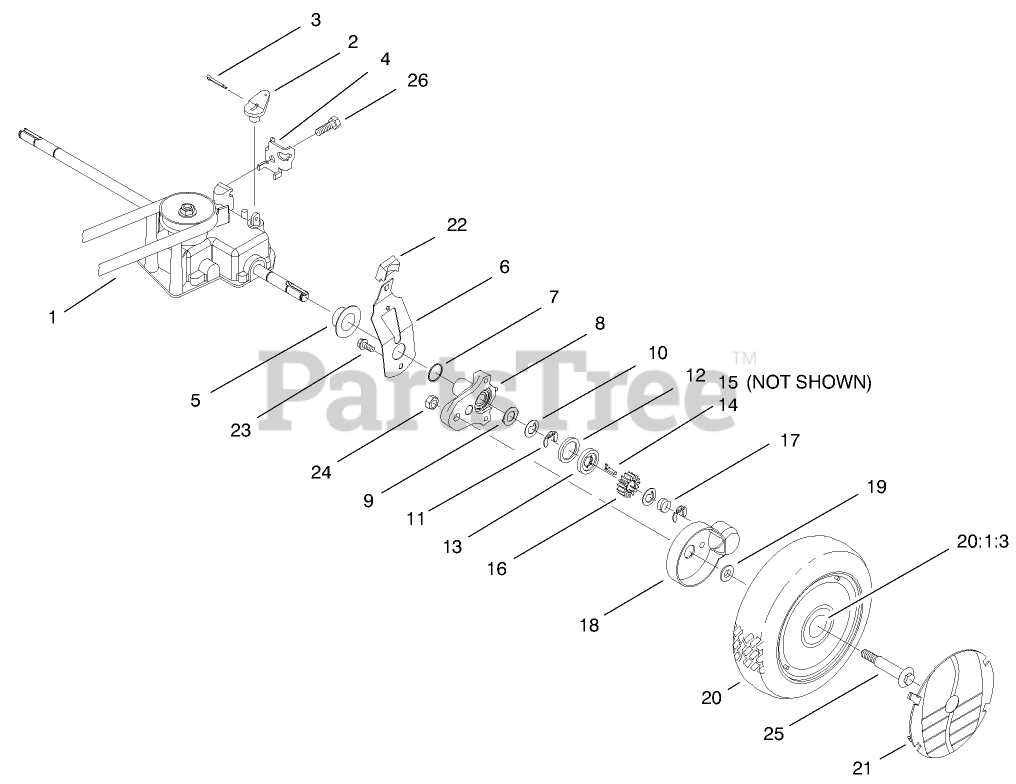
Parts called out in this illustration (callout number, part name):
1	V-BELT
2	LEVER-SHIFT
3	PIN-COTTER
4	CLAMP-CABLE
5	CAP-END
6	SPRING ARM ASM
7	O-RING
8	PIVOT ARM ASM
9	WASHER-ARM, PIVOT
10	WASHER-THRUST, KEYED
11	RING-RETAINING,CLIP
12	RING-FRICTION
13	WASHER-CLUTCH
14	KEY-ROCKING, LH
15	KEY-ROCKING, RH
16	GEAR-PINION
17	SPRING-COMPRESSION
18	COVER-WHEEL
19	SPACER-COVER, WHEEL
20	WHEEL AND GEAR ASM
20:1:3	BUSHING
22	KNOB-ARM
23	SCREW-HWH
24	LOCKNUT
25	BOLT-SHOULDER
26	SCREW-HWHTF
